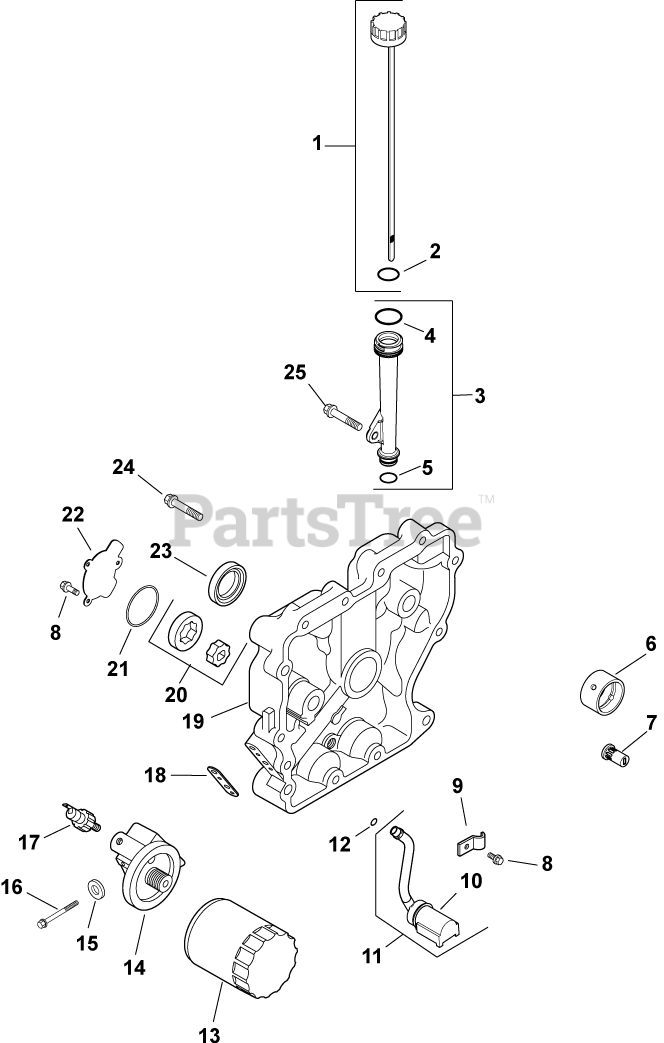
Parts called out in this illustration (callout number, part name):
1	KIT, OIL FILL CAP ASSEMBLY
2	O-RING, UPPER OIL FILL TUBE
3	KIT, OIL FILL TUBE - USE 12 755 113-S
4	O-RING, UPPER OIL FILL TUBE
6	BEARING, CRANKSHAFT
7	VALVE, OIL PRESSURE RELIEF
8	SCREW,FLG THD FRM M5X0.8X16-(#25086398S)
10	PICK-UP, OIL SCREEN
11	KIT, OIL PICK-UP
12	O-RING (.5" DIA)
13	OIL FILTER
14	ADAPTER - DISCONTINUED
16	SCREW, FLG M6X1.0X60
17	SENSOR, OIL PSI
18	GASKET, OIL FILTER ADAPTER
19	CLOSURE PLATE ASSEMBLY - DISCONTINUED
20	PUMP ASSEMBLY, OIL
21	O-RING (1.78" DIA)
22	COVER, OIL PUMP
23	SEAL, OIL
24	SCREW, FLG M8X1.25X45
25	SCREW, FLG M8X1.25X50
